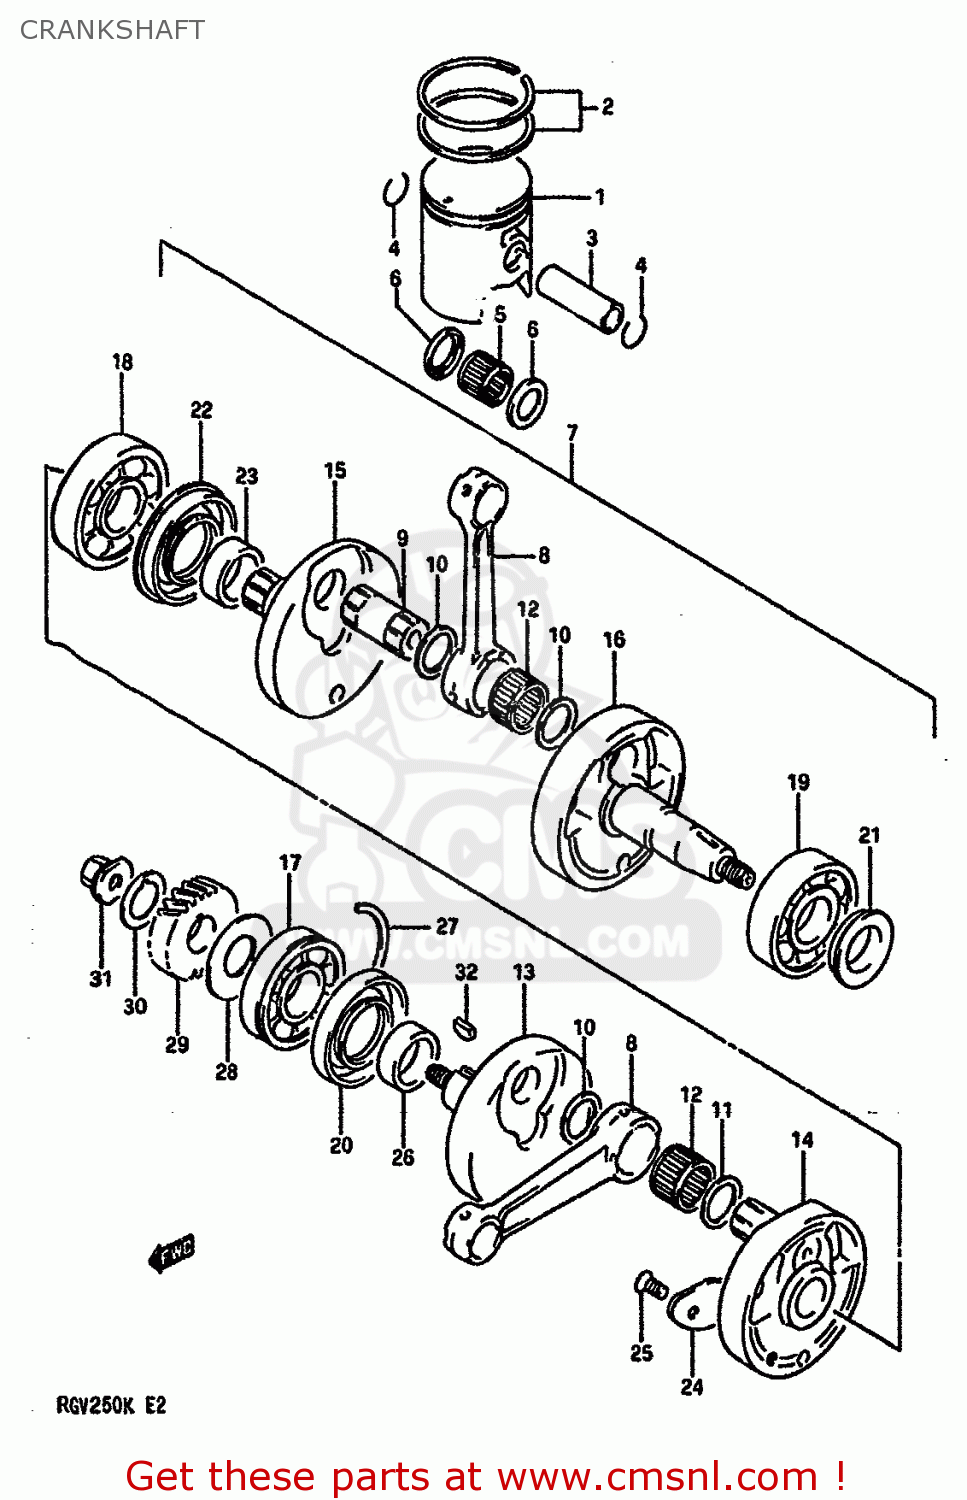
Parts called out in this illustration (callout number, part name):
1	PISTON
2	RING SET,PISTO
3	PIN,PISTON
4	RING,SNAP 16MM
5	BEARING,PISTON PIN
6	WASHER
7	CRANKSHAFT ASSY
8	ROD,CONNECTING
9	PIN,CRANK
10	WASHER(22X27.5X1.5)
11	WASHER(22X27.5X2)
12	ROLLER BEARING (22X28X1
13	CRANKSHAFT,RH
14	WEB,CRANKSHAFT
15	CRANKSHAFT,MIDDLE
16	CRANKSHAFT,LH
17	BEARING(25X62X17)
18	BEARING (25X62X18)
19	BEARING(25X62X17)
20	SEAL,OIL(32X62X6X7.5)
21	OIL SEAL (25X36X6)
22	OIL SEAL (33X62X10)
23	SPACER (25.5X33X12)
24	BALANCER,CRANKSHAFT
25	SCREW
26	SPACER(25.2X32X9)
27	C RING
28	SHIM(20X48X0.5)
29	GEAR,PRIMARY DRIVE
30	WASHER
31	NUT
32	KEY
